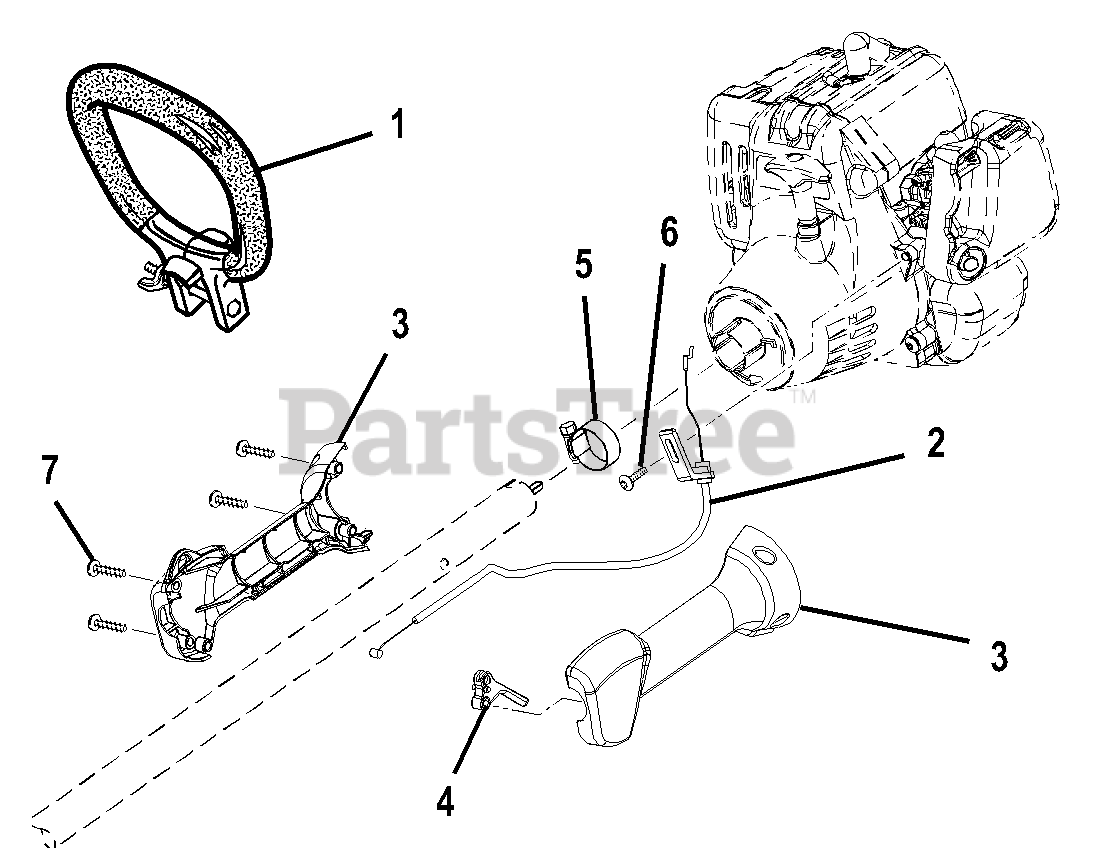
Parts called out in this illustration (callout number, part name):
1	Handle Assembly
2	Throttle Cable
3	Handle Assemble
4	Trigger
5	Clamp - Boom
